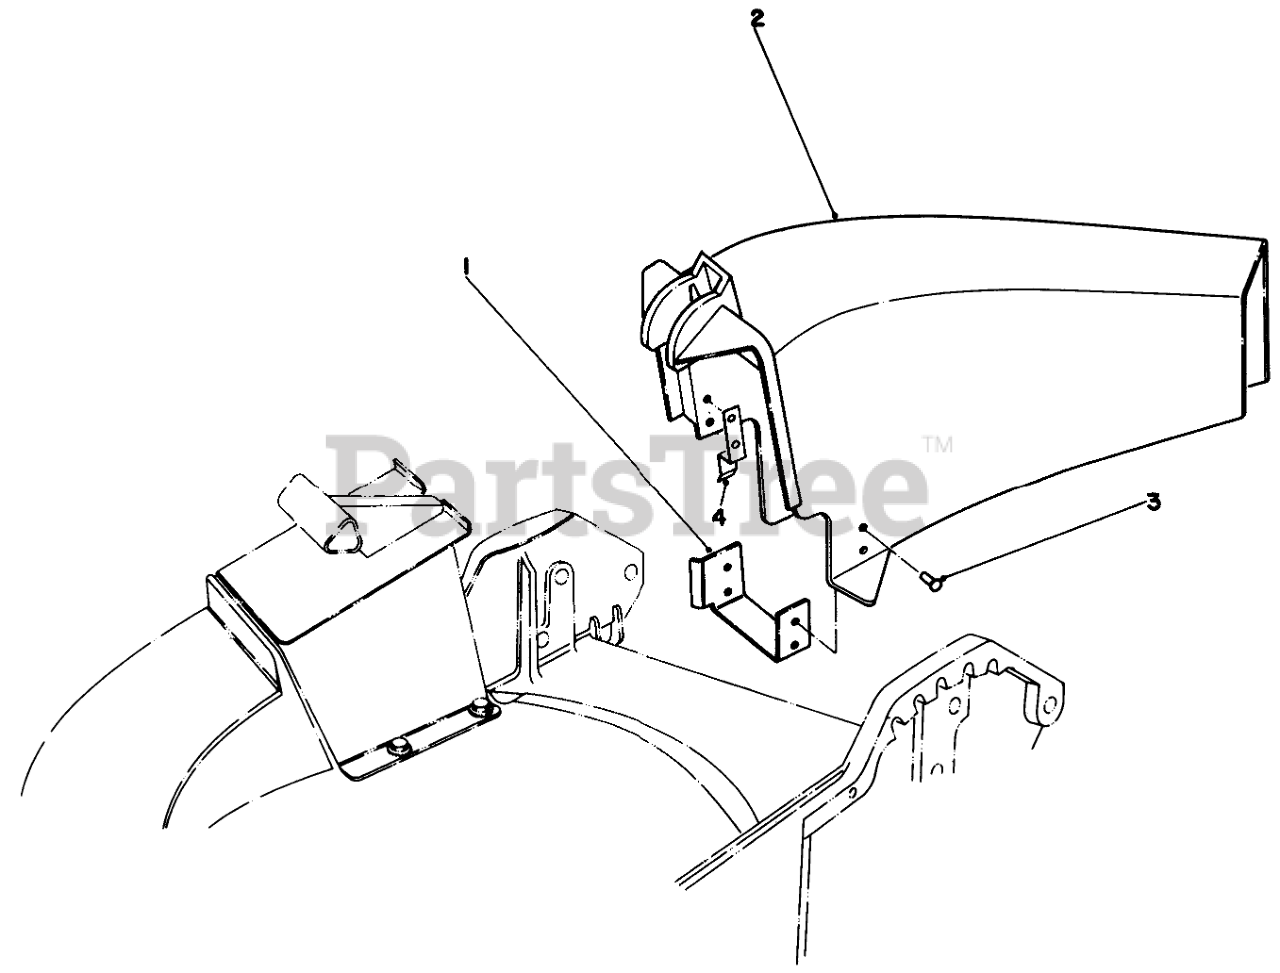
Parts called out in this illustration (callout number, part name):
1	CHUTE BRACKET
2	Chute Discharae
3	RIVET
4	CHUTE TAB
